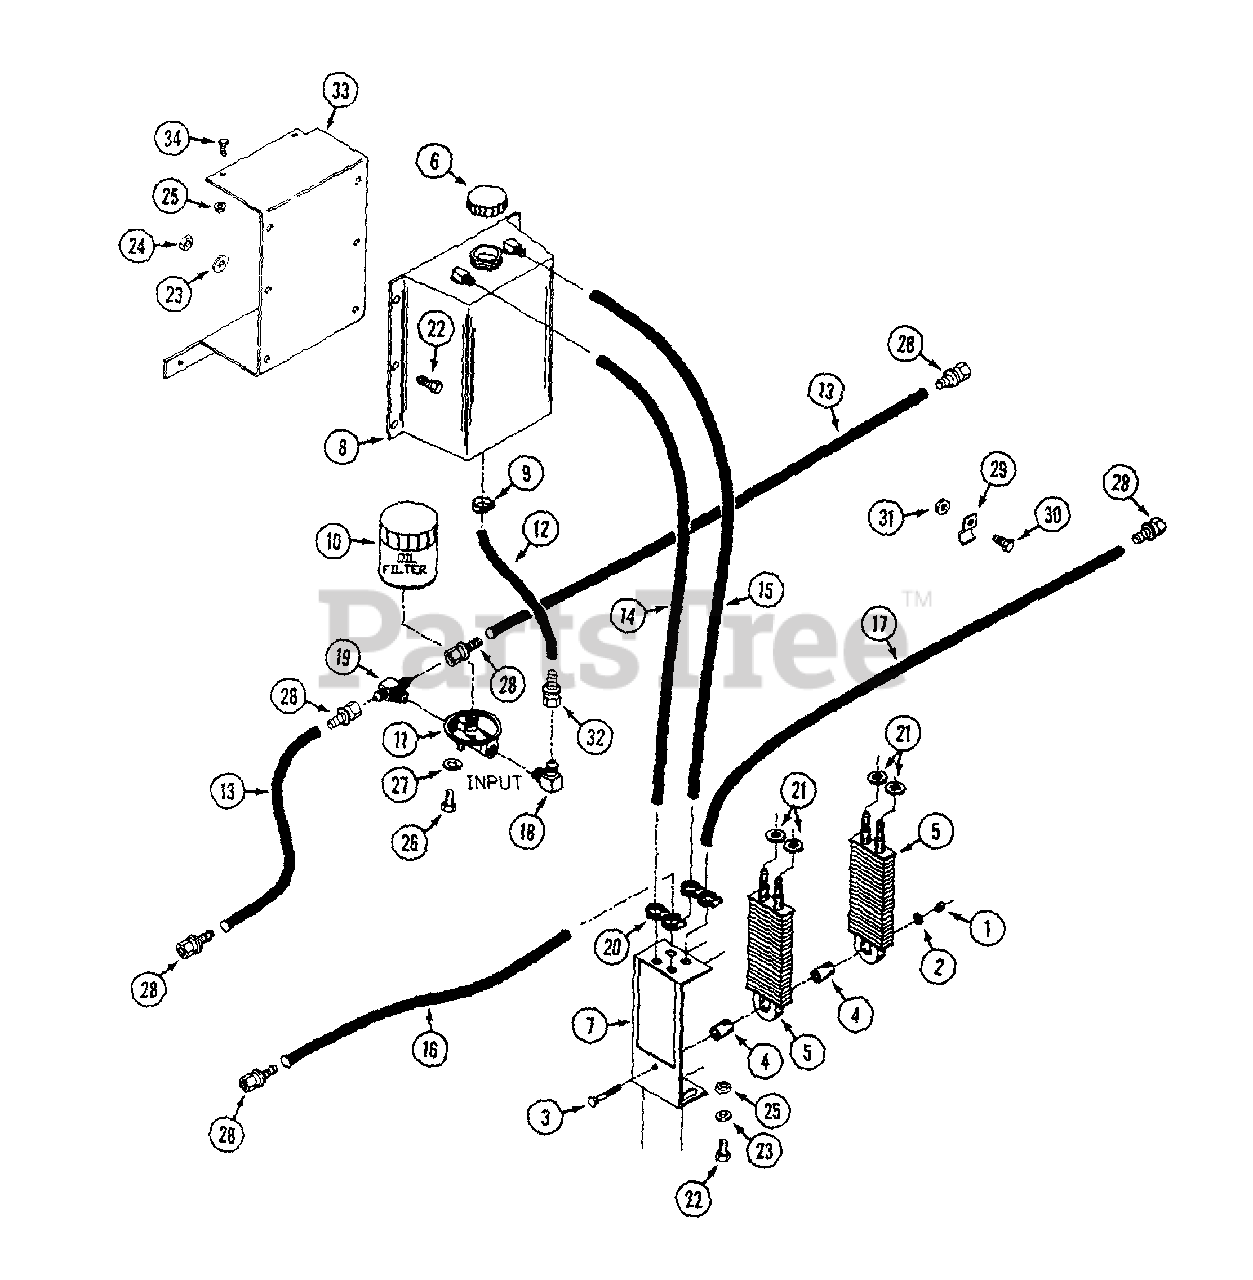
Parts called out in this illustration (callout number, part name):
1	NUT - lock 5/16"
2	WASHER - 5/16"
3	BOLT - 5/16" - 18 x 2-3/4"
4	BUSHING - rubber
6	CAP - oil tank
7	MOUNT - oil cooler
9	CLAMP - hose 5/8"
11	HEAD - oil filter
12	HOSE - 5/8" x 11"
13	HOSE - hydraulic 3/8" x 13"
14	HOSE - hydraulic 3/8" x 25"
15	HOSE - hydraulic 3/8" x 27"
16	HOSE - hydraulic 3/8" x 38"
17	HOSE - hydraulic 3/8" x 24"
18	FITTING - male 90° adapter
19	FITTING - male tee adapter
20	CLAMP - hose 3/8"
21	GROMMET - 1/2" ID x 1" OD
22	BOLT - 1/4" - 20 x 3/4"
23	WASHER - 1/4"
24	NUT - 1/4" - 20 lock
25	NUT - 1/4" - 20 flange lock
26	BOLT - 1/4" - 20 x 1/2" flange
27	LOCKWASHER - 1/4"
28	FITTING - 3/8" hose barb x 3/8" FM JIC
29	CLIP - "J"
30	BOLT - 5/16" x 18 x 3/4"
31	NUT - 5/16" - 18 flange lock
32	FITTING - 5/8" hose barb x 1/2" FM JIC
33	MOUNT - oil tank
34	BOLT - 1/4" - 20 x 1/2"
